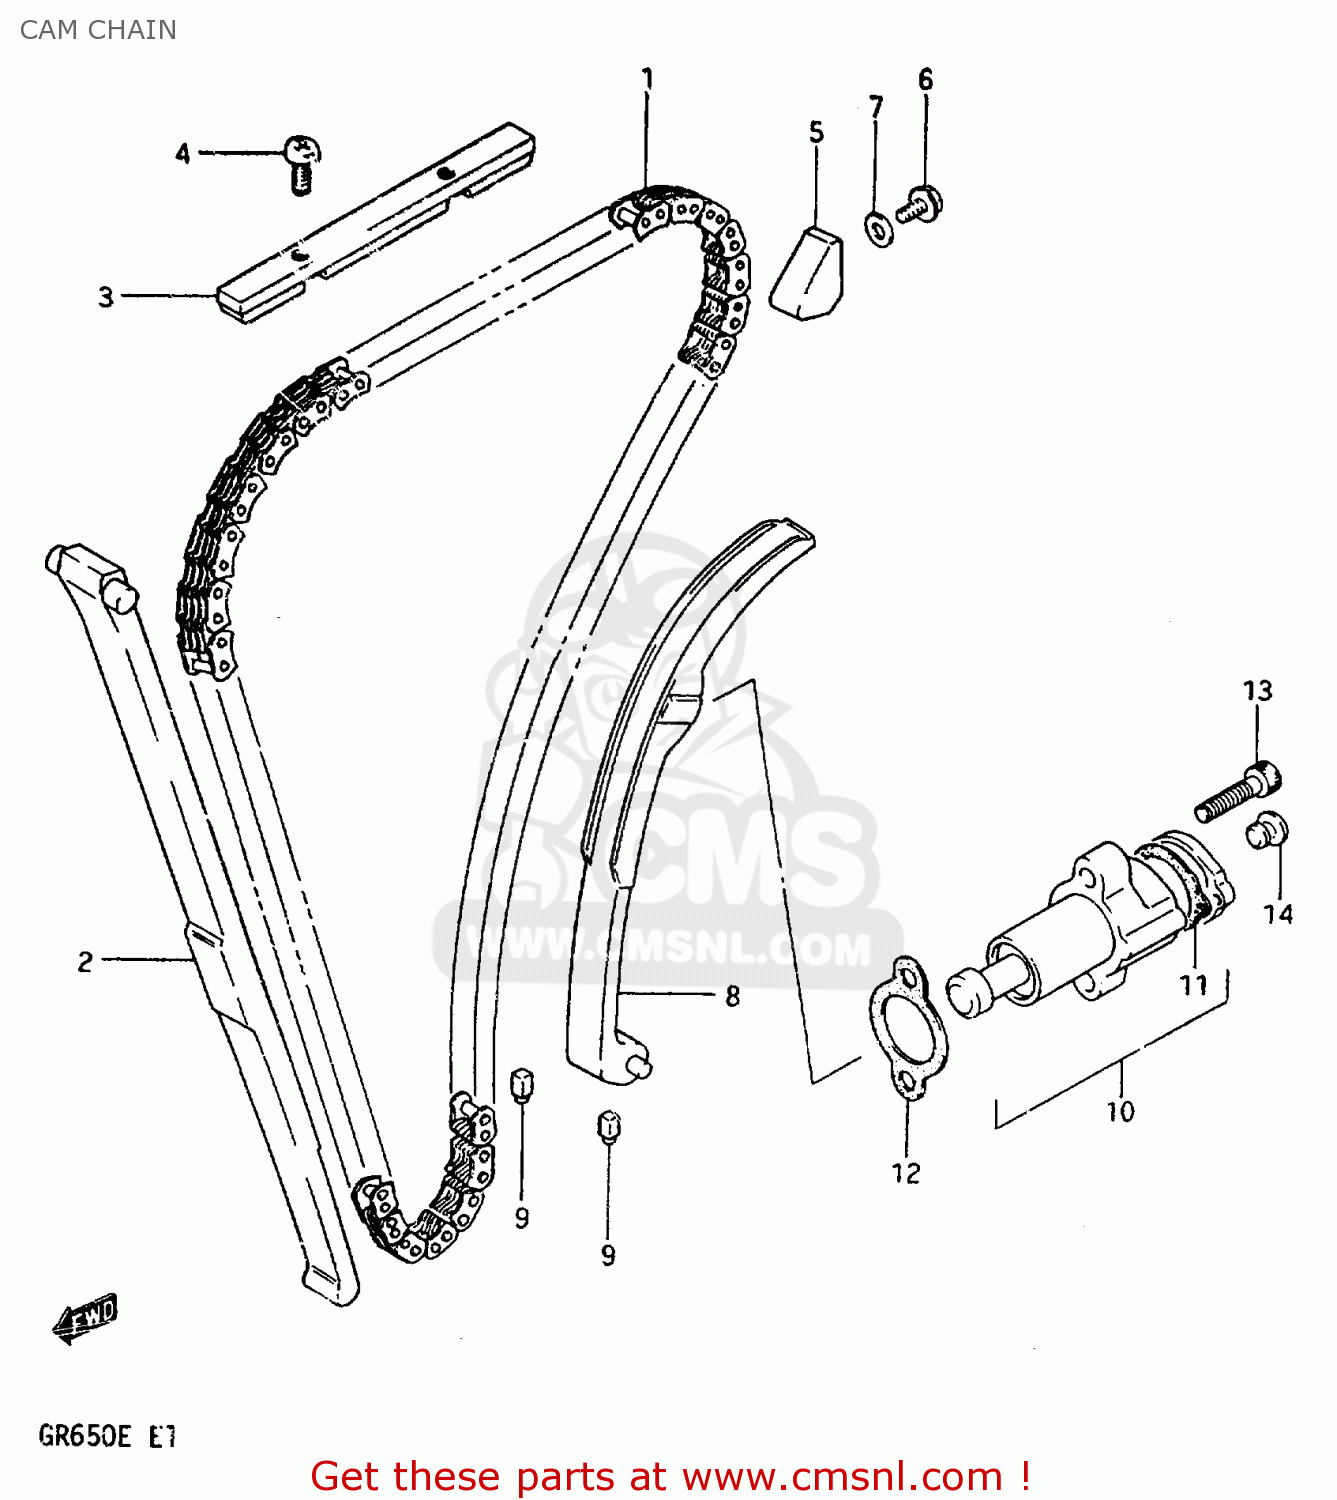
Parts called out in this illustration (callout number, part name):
1	CHAIN,CAMSHAFT DRIVE
2	GUIDE,CAM CHAIN NO.1
3	GUIDE,CAM CHAIN NO.2
4	SCREW
5	GUIDE,CAM CHAIN NO.3
6	BOLT 6X12
7	WASHER
8	TENSIONER,CAM CHAIN
9	CUSHION,CAM CHAIN TENSIONER
10	ADJUSTER ASSEMBLY,TENSIONER
11	GASKET,ADJUSTER CAP (MCA)
12	GASKET,TENSIONER ADJUSTER (MCA)
13	BOLT
14	PLUG,ADJUSTER
